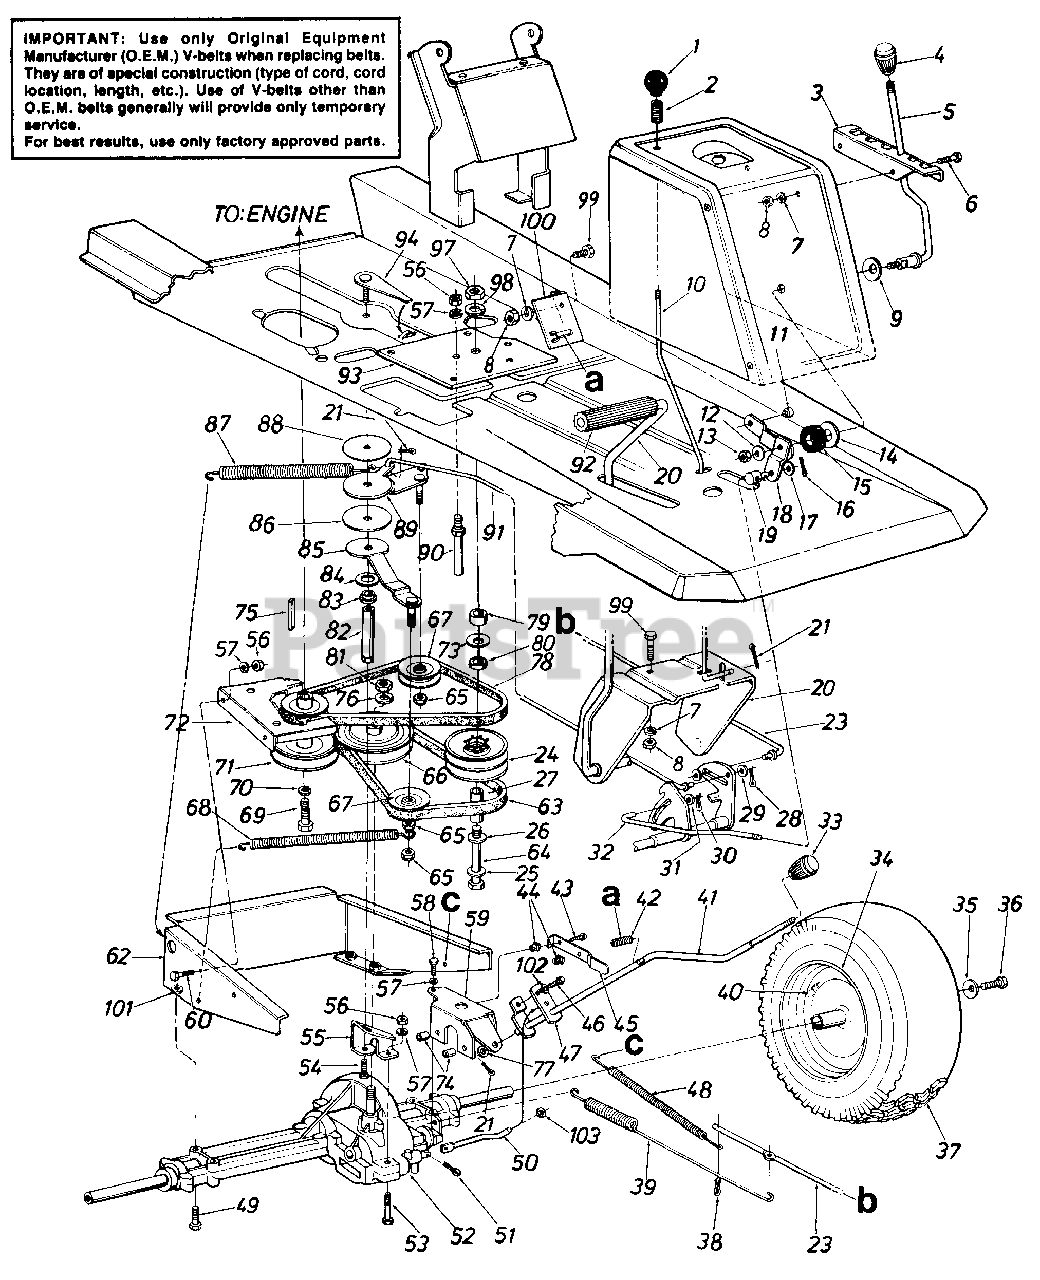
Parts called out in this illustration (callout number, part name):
1	Ball Knob 1/4-20 Thd. 1.25'
2	Compression Spring
5	Speed Control Lever
6	Truss Mach. Scr. 5/16-18 x .75" Lg.
7	L-Wash. 5/16" I.D.
8	Hex Nut 5/16-18 Thd.
9	Bell-Wash. .345" I.D. x .88"
10	Brake Locking Rod
12	Bell-Wash. .345" I.D. x .08"
13	Hex Cent. L-Nut 5/16-18 Thd.
14	Fl-Wash. .531" I.D. x 1.25" O.D.
15	Rubber Washer
16	Intern. Cotter Pin 1/2" Dia.
17	Fl-Wash. .34" I.D. x .68" O.D.
18	Speed Control Lever Brkt. Ass'y.
19	Ferrule-Engagement
20	Clutch/Brake Pedal Ass'y.
21	Cotter Pin 3/32" Dia. x .75"
23	Brake Rod
24	Variable Speed Pulley Ass'y.
25	Fl-Wash. .4" I.D. x 1.25" O.D.
26	Thrust Brg. 1.25" O.D. x .56" I.D.
27	Spacer Sleeve 2.71
28	Cotter Pin 1/8" Dia. x 1.25
29	Fl-Wash. .34" I.D. x .60" O.D.
30	Intern. Cot-Pin 5/16" Dia.
31	Fl-Wash. .34" I.D. x .60" O.D.
32	Speed Control Link
33	Shift Knob
34	Rear Wheel Rim Only
35	Bell-Wash. .345" I.D. x .88"
36	Hex L-Bolt 5/16-24 x .75" Lg.
37	Rear Wheel Ass'y.-Comp.
38	Cotter Pin 1/8" Dia. x 1.25"
39	Extension Spring 17.0" Lg.
40	Air Valve
43	C Sink ABS-Tap Scr. #8 x .50" Lg.
44	Push-in Nut #10
45	Spring Switch
46	Hex Bolt 1/4-20 x .50" Lg.
47	Shift Lever Adjusting Link
48	Ext. Spring 8-1/4" Lg.
49	Hex Bolt 5/16-18 x 2.5" Lg.
50	Shift Rod
51	Intern. Cotter Pin
52	Transaxle
53	Hex Bolt 1/4-20 x 1.75" Lg.
54	Hex Bolt 3/8-24 x .75" Lg.
57	L-Wash. 1/4" I.D.
58	Self-Tap Mach. Scr. Type "C" 1/4-20 x 1.37" Lg.
59	Shift Lever Support Brkt.
60	Hex Bolt 1/4-20 x 1.00" Lg.
64	Hex Bolt 3/8-16 x 4.5" Lg.
65	Hex Ins. L-Nut 3/8-24 Thd.
66	5/8 V-Pulley 500" I.D. x 6"
67	V-Belt Idler .38" I.D. x 3.06"
68	Ext. Spring .50" O.D. x 6.37"
69	Hex Bolt 7/16-20 x 1.00" Lg.
70	L-Wash. 7/16" I.D.
71	Engine Pulley.500" O.D. & 3.56" O.D.
72	Upper Eng. Belt Guard
73	Bell-Wash. .4" I.D. x 1.12" O.D.
74	Spacer .256" I.D. x .50" O.D.
75	Sq.-Key 1/4" x 2.00" Lg.
76	L-Wash. 1/2" I.D.
77	Fl-Wash. .469" I.D. x .88" O.D.
78	V-Belt
79	Spacer 1.00" x .380" O.D.
80	Thrust Wash. .56 I.D. x 1.25" O.D.
81	Hex Nut 1/2-20 Thd.
82	Torque Rod
83	Flange Bearing .378
84	Fl-Wash. .640" I.D. x 1.24"
85	Idler Bracket Ass'y.
86	Thrust Wash. .635" I.D.
87	Extension Spring 7.58" Lg.
88	Thrust Wash. .385" I.D.
89	Idler Bracket Ass'y. For Clutch
90	Belt Guard Pin 1/4" Dia.
91	Clutch Rod
92	Foot Pad
93	Mtg. Brkt. Variable Pulley
98	L-Wash. 3/8 Heavy Duty
99	Hex Bolt 5/16-18 x .75" Lg.
100	Shift Lever Spring Brkt.
101	Hex Sems Nut 5/16-18 Thd.
102	Bell-Wash. .265" I.D. x .75" O.D.
103	Push on Retaining Ring
